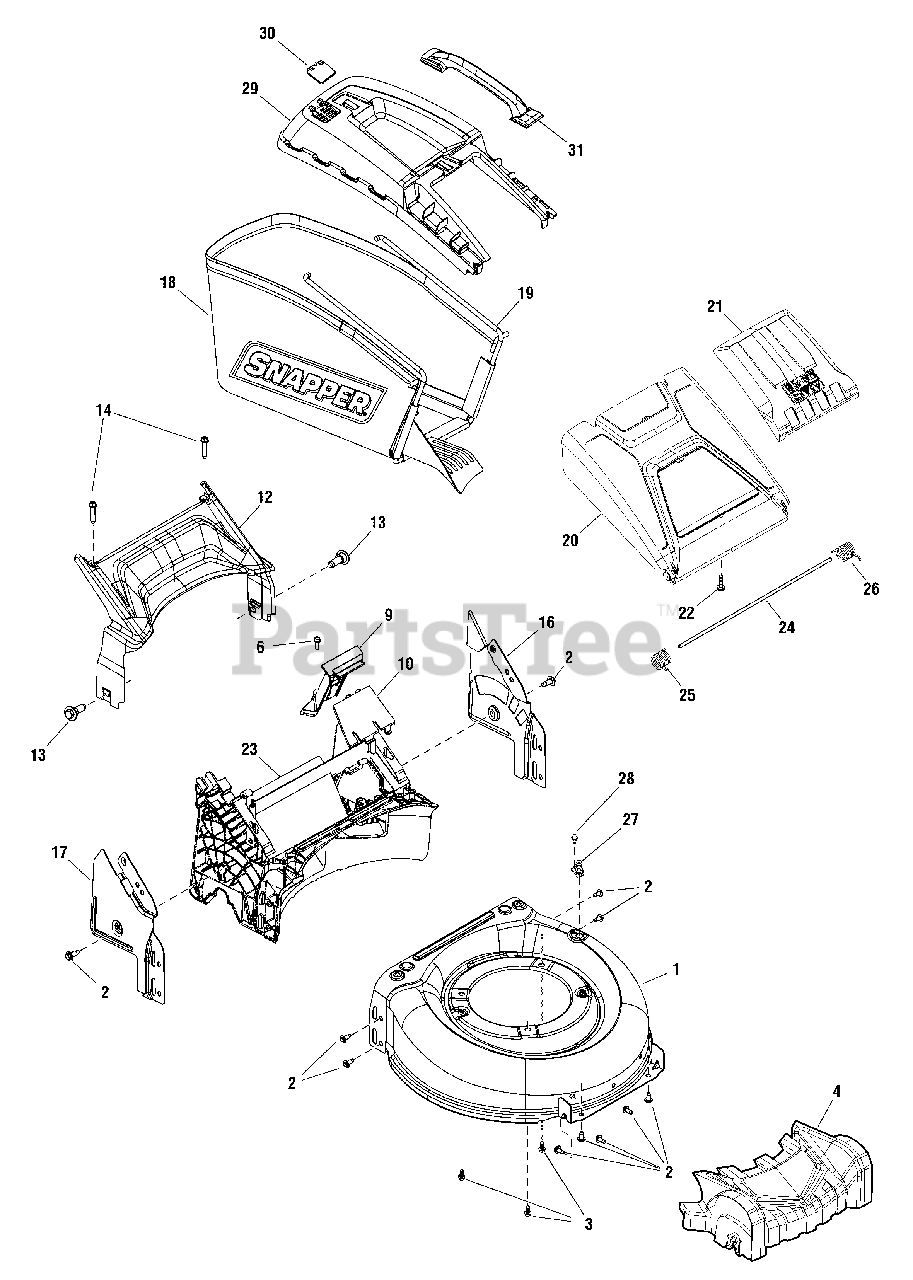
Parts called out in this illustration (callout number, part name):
2	SCREW, Hex Head
3	SCREW, 3/8-16 x 1
4	FRONT COVER, Deck
6	SCREW, 1/4-15X3/4, Self-Tapping, BZ
9	COVER, Rear
10	COVER, Front
12	COVER, Rear
13	SCREW, 5/16-14
14	SCREW, 1/4-15 x 1-1/4
16	SUPPORT, Handle, LH
17	SUPPORT, Handle, RH
20	REAR FLAP
21	COVER, Gray
22	SCREW #10-16 x 3/4
23	GUIDE, Rear
25	TORSION SPRING, RH
26	TORSION SPRING, LH
27	NOZZLE, Wash
28	SCREW, 1/4-20 x 1/2
29	COVER, Bagger
30	INDICATOR, Full Bag
